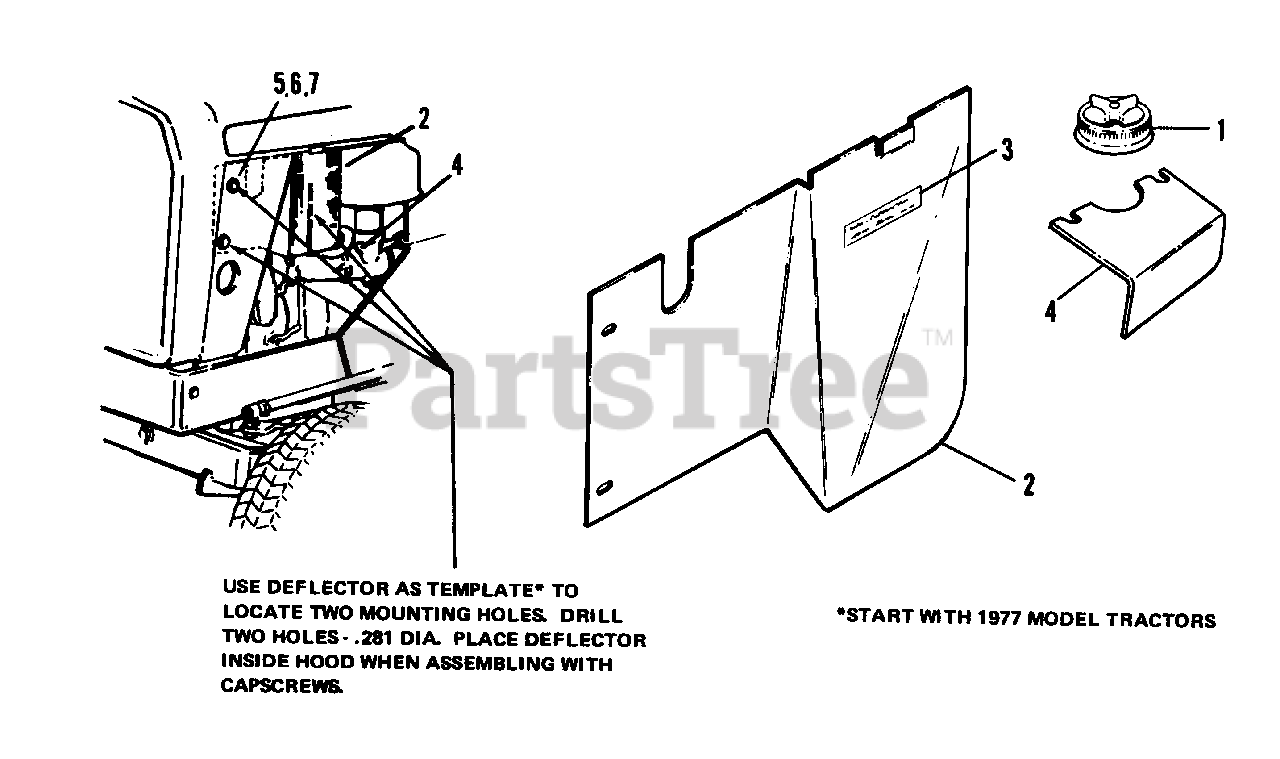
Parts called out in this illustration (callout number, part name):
1	CAP, Fuel Tank
2	DEFLECTOR
3	DECAL, Shield
4	SHIELD, Carburetor
5	NUT, Hex, 1/4-20
6	LOCKWASHER. Spring, 1/4
7	CAPSCREW, Hex Hd., 1/4-20 x 1/2
